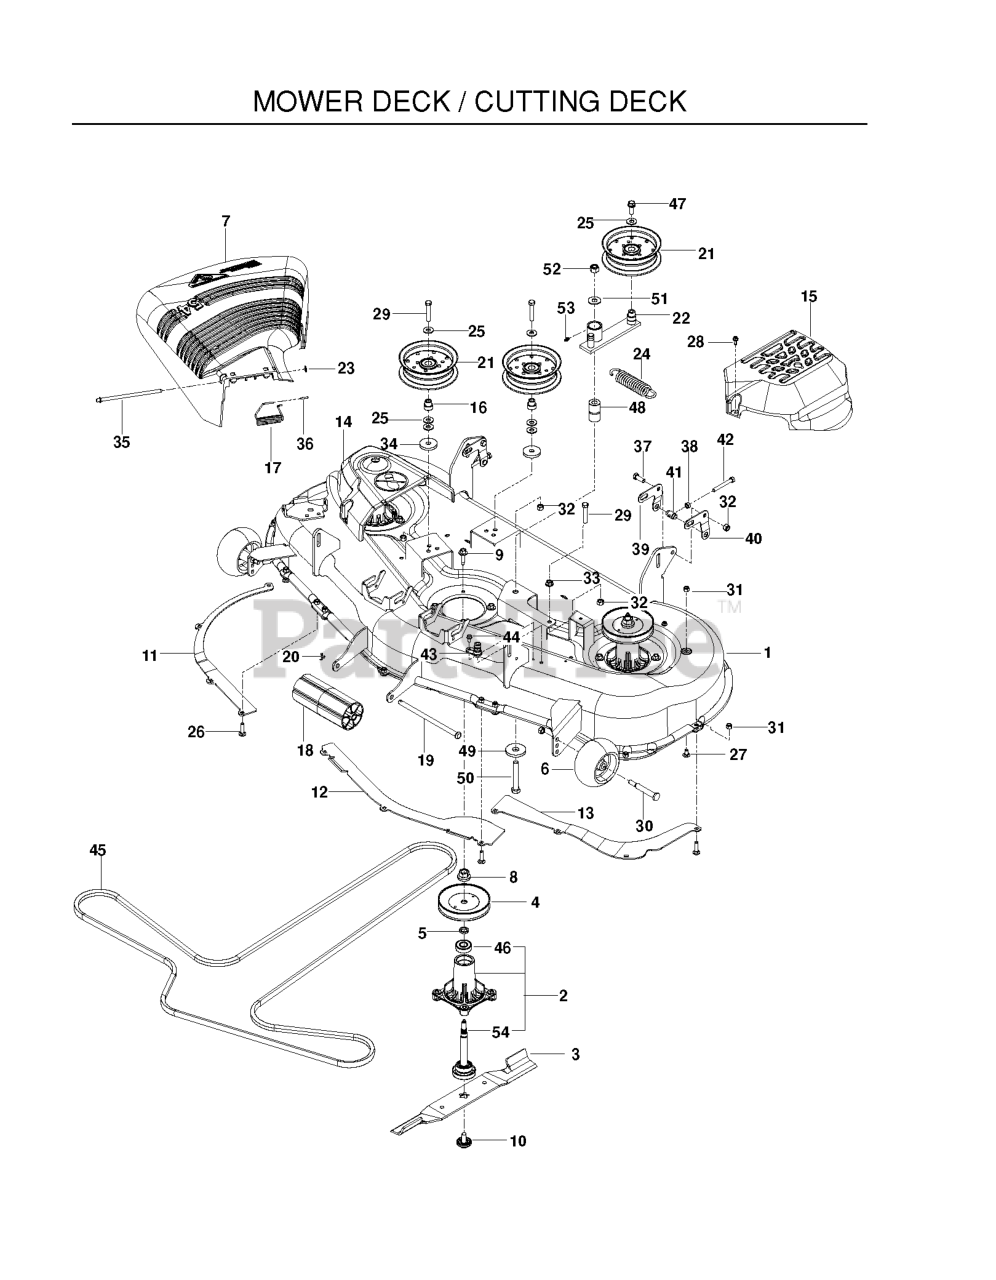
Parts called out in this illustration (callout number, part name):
1	DECK.SVC W/DECALS.54.MZ.ORANGE
2	MANDREL GREASABLE
3	BLADE.BAGGING.54"
4	PULLEY
5	WASHER-SPACER
6	GAUGE WHEEL
7	DEFLECTOR, 54"
8	LOCKNUT - 9/16
9	WASHER HEAD SCREW
10	BOLT.WASHER.ASM.7/16-2
11	BAFFLE, RIGHT 54"
12	BAFFLE, CENTER, 54"
13	BAFFLE LEFT 54
14	COVER.MANDREL.RH.DECK.54"
15	COVER.MANDREL.LH.DECK.54"
16	IDLER BUSHING
17	TORSION SPRING
18	NOSE ROLLER 48"
19	NOSE ROLLER ROD
20	RP_COTTER PIN 1/8 X 3/4
21	PULLEY, IDLER
23	PUSH NUT
25	WASHER 3/8 FLAT
26	BOLT, CARRIAGE 5/16X1-1/4
27	CARRIAGE BOLT 5/16C X 5/8"
28	SCREW- 1/4-20 X 5/8
29	HCS 3/8C X 2
30	SHOULDER BOLT 1/2X2-5/8 ZD SPE
31	NUT 5/16 NYLOC
32	NUT 3/8-16 NYLOC
33	NUT 3/8C WHIZ
34	SPINDLE WASHER
35	ROD, HINGE
36	CAP-SLEEVE
37	HCS 3/8-16X1.GRD.5.ZD
38	NUT 5/16C HEX
39	PITCH, ADJUST, RT
40	PITCH, ADJUST, LT
41	TRUNION, PITCH
42	HCS 5/16-18 X 2 1/2 TPBLT
43	PORT.WASHOUT
44	BOLT 1/4-20 X 1/2 HWST
45	BELT.DECK.EL=152.9
46	BEARING, BALL
47	4CS 3/8C X 1 SERRATED HEAD
48	PIVOT BUSHING
49	WASHER, SUPPORT
50	HCS 1/2C X 3 1/4
51	WASHER 1/2 FLAT
52	NUT 1/2-13 HEX NYLOC ZD
53	ZERK
54	GREASABLE MANDREL SHAFT
